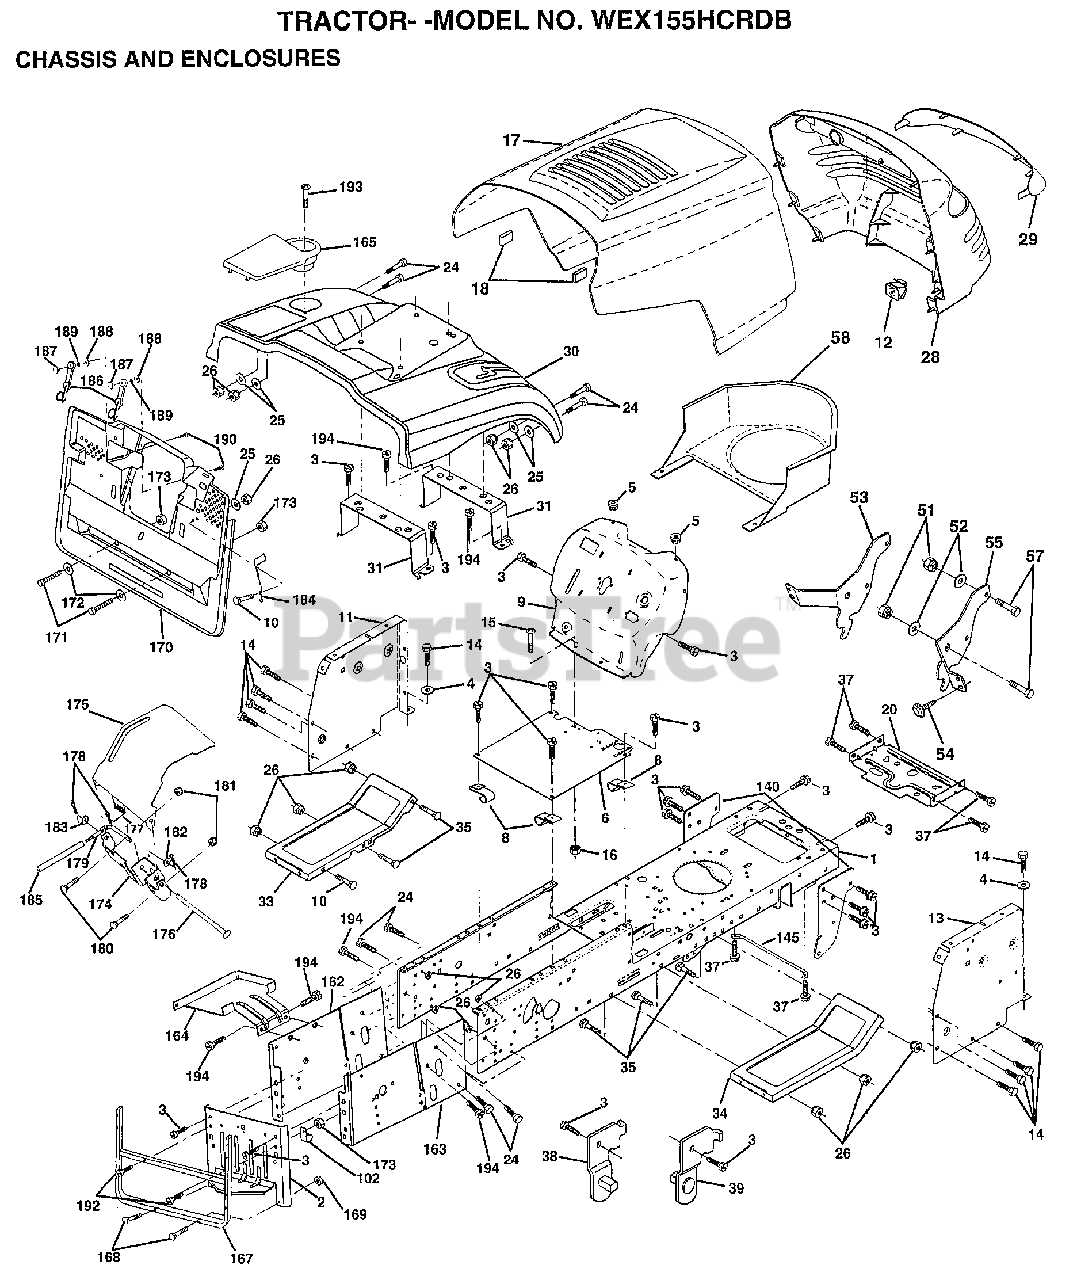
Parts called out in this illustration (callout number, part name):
1	CHASSIS.STAMPING
2	DRAWBAR.CRD
3	SCREW
4	WASHER
5	BUMPER-HOOD/DASH
6	SADDLE
8	"CLIP,INSULATOR"
9	DASH.SILKSCREEN
11	"PANEL-DASH,LH"
12	CLIP.TINNERMAN
14	SCREW LT
15	SCREW
17	HOOD.STEEL.ASSY
20	"PLATE-MTG,BATT/FU"
24	BOLT
25	WASHER
26	NUT
28	GRILLE-MS428
29	LENS.GRILLE.PRIVATE LABEL
30	FENDER.CRD.GREEN
31	BRKT.SUPT.FENDER.CRD
33	FOOTREST.LH.LT/GT
34	FOOTREST.RH.LT/GT
35	BOLT
37	SCREW LT
38	BRACKET ASM LH
39	BRACKET ASM RH
51	NUT
52	WASHER
53	BRACKET.GRILLE.LH
54	SCREW.HEX.WS.HD
55	BRACKET.GRILLE.RH
58	AIR DUCT
102	CLIP T
140	BRKT SUSPENSION
145	"ROD POVOT,CHASSIS"
162	BRKT.EXT.CHASSIS.LH.CRD
163	BRKT.EXT.CHASSIS.RH.CRD
164	SUPPORT.BATTERY.CRD
165	COVER.BATTERY.CRD.BLACK.LT
167	SUPT.ASM.BACKPLATE
168	BOLT-RD HD SQ NK
170	COVER.BACKPLATE.BLACK
171	BOLT.HEX.3/8-16X2-1/2
173	NUT
174	BRKT.SWITCH.FBI.CRD
175	GRUARD.DOOR.REAR.CRD
176	HINGE PIN
177	SPRING.COVER.LH
179	ROD.PIVOT.FBI.CRD
182	WASHER.385X.625
183	WASHER
184	BRKT.ACTUATOR.BAG.CRD
185	TUBE.LEVER.SWCH.FBI.CRD
186	LATCH ASSY.BAGGER
187	WELDNUT
188	WASHER #10
189	LOCKWASHER
190	SCREW
192	SCREW LT
193	SCREW LT
194	SCREW
